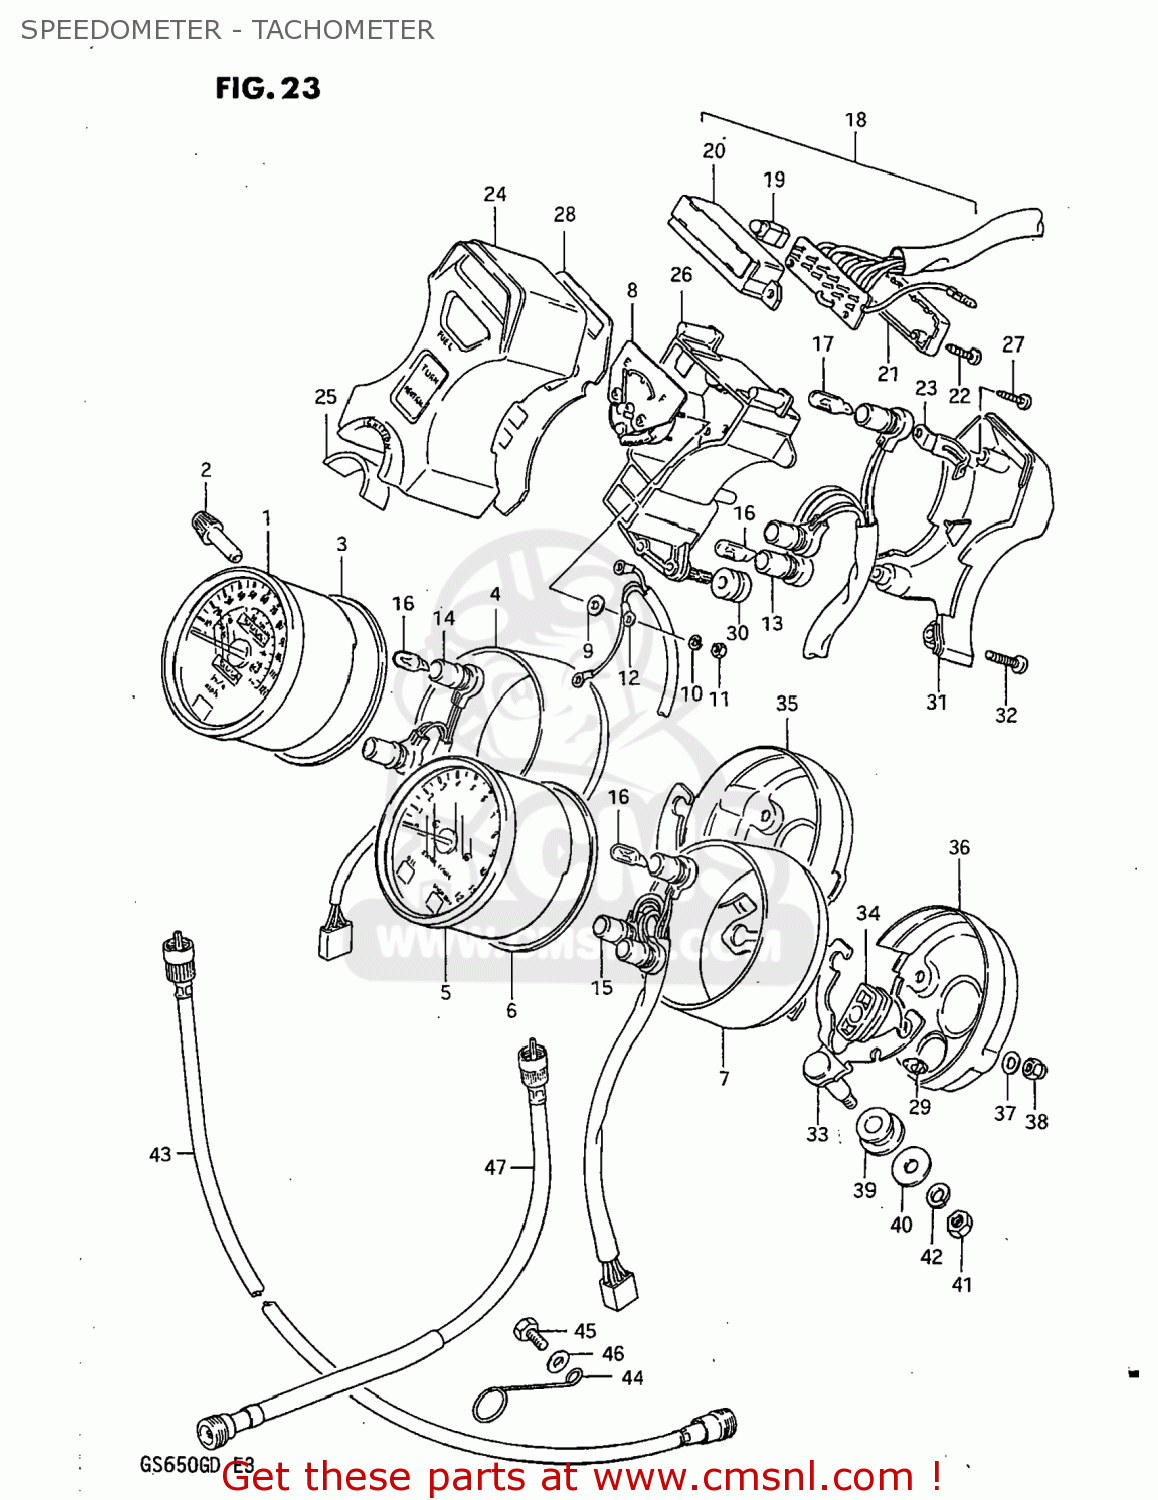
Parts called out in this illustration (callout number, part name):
1	SPEEDOMETER ASSEMBLY
2	KNOB
3	CUSHION,SPEEDOMETER
4	COVER,SPEEDOMETER
5	TACHOMETER
6	CUSHION,SPEEDOMETER
7	COVER,TACHOMETER
8	METER,FUEL
9	WASHER,FUEL METER
10	LOCK WASHER
11	NUT 3MM
12	LEAD WIRE,FUEL METER
13	SOCKET
14	SOCKET,SPEEDOMETER
15	SOCKET,TACHOMETER
16	BULB(12V3.4W,T10)
17	BULB(12V1.7W,T10,WB121)
18	INDICATOR ASSEMBLY,GEAR POSITION
19	BULB(14V1.12W,BQ041-32503B)
20	CASE,GEAR INDICATOR
21	COVER,LWR
22	SCREW,GEAR INDICATOR
23	CLAMP,CORD
24	CASE,PILOT BOX
25	SEAL,IGNITION SWITCH
26	CASE,PILOT BOX,INNER
27	SCREW,INDICATOR
28	PLATE,PILOT BOX
29	CUSHION,METER
30	CUSHION,PILOT BOX
31	COVER,PILOT BOX,UNDER
32	SCREW
33	BRACKET,COMBINATION METER
34	CUSHION,METER
35	COVER,METER,UNDER
36	PLATE,TACHOMETER UNDER
37	WASHER
38	NUT
39	CUSHION,METER BRACKET
40	WASHER (8.5X29X1.6)
41	NUT
42	LOCK WASHER
43	CABLE ASSEMBLY,SPEEDOMETER
44	CLAMP,SPEEDOMETER CABLE
45	BOLT, UPPER
46	WASHER
47	CABLE ASSEMBLY,TACHOMETER
